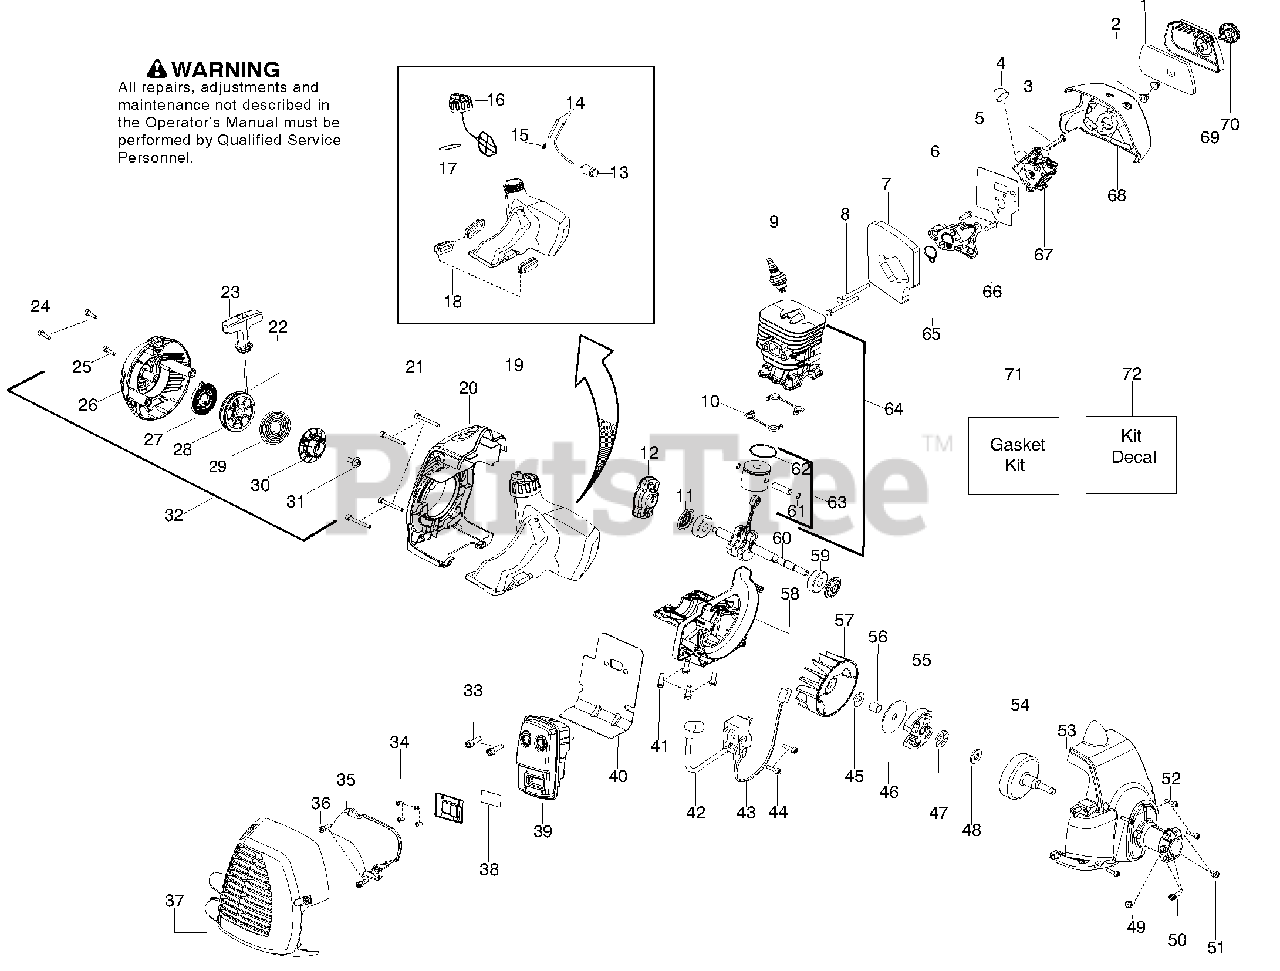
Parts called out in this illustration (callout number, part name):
2	Nut-Carb. Screw
3	Lever - Choke
4	Bulb-Purge
5	Kit-Carb. Gasket
6	Adaptor-Carb.
7	Foam-Gasket (kit)
9	Plug-Spark (RCJ-8Y)
10	Seal-Cylinder (kit)
11	Seal-Crankshaft (kit)
12	Assy-Starter Pawl
13	Assy-Fuel Filter
14	Kit-Fuel Line
15	Fitting-Fuel line
16	Assy-Cap w/ret
17	O-ring - Fuel Cap (kit)
18	Isolator-Fuel Tank
19	Kit-Fuel Tank Assy.
20	Shroud-Rear
22	Kit-Rope
23	Handle-Starter
26	Hsg.-Starter (KIT)
27	Kit-Spring
28	Kit-Starter Pulley
29	Spring - Driver
30	Pulley-Driver
32	Assy-Starter Hsg.
33	Bolt-Muffler
34	Screw
35	Shield-Heat
37	Kit - Muffler Guard
38	Kit-Spark
39	Kit-Muffler
40	Gasket-Paper Met.(kit)
43	Assy-Leadwire
46	Washer-Clutch
47	Bearing - Thrust
48	Washer - Thrust
53	Assy-Fan Housing
54	Assy-Clutch Drum
55	Assy-Clutch
58	Crankcase-Cast
60	Assy-Crankshaft
61	Retainer-Piston Pin
62	Ring-Piston
63	Kit-Piston
64	Kit-Piston/Cyl.
65	Seal-adaptor (kit)
67	Kit-Carb.
69	Cover-Air Box
71	Kit-Gasket
72	Kit - Decal
